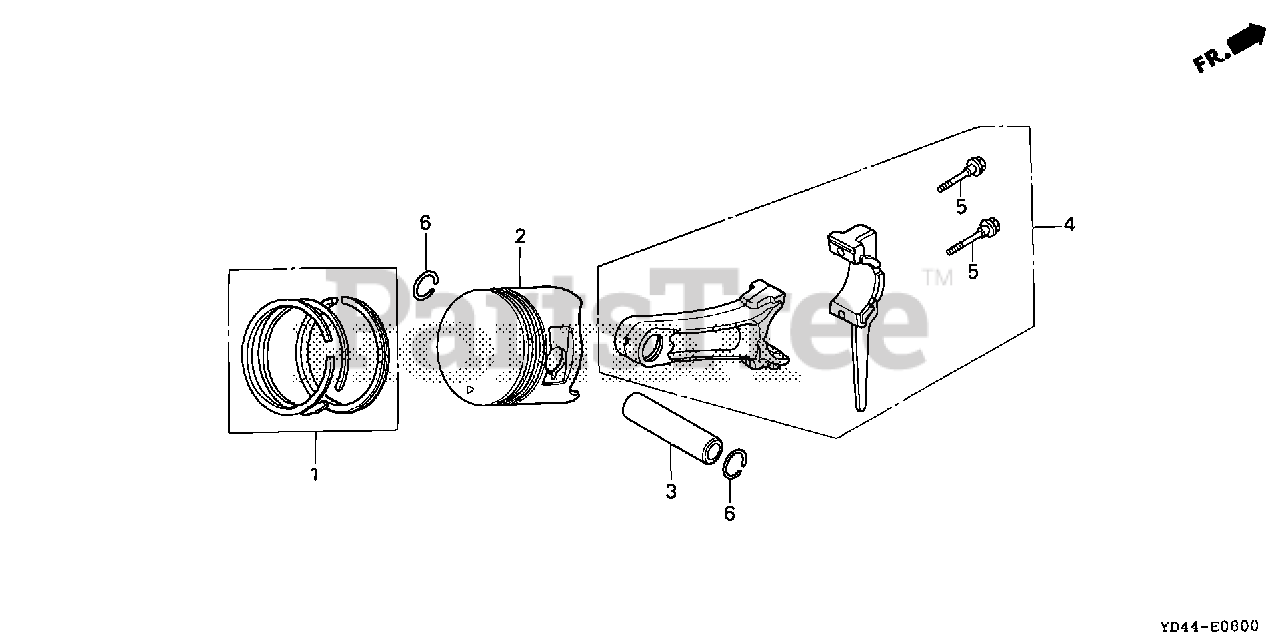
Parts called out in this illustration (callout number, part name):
1	RING SET, PISTON (STD) (TEIKOKU)
1	RING SET, PISTON (0.25) (TEIKOKU)
1	RING SET, PISTON (0.25) (RIKEN)
1	RING SET, PISTON (0.50) (TEIKOKU)
1	RING SET, PISTON (0.50) (RIKEN)
1	RING SET, PISTON (0.75) (TEIKOKU)
1	RING SET, PISTON (0.75) (RIKEN)
2	PISTON (STD)
2	PISTON (0.25)
2	PISTON (0.50)
2	PISTON (0.75)
3	PIN, PISTON
4	ROD ASSY., CONNECTING (STD)
4	ROD ASSY., CONNECTING (0.25 LOWER SIZE)
5	BOLT, CONNECTING ROD
6	CLIP, PISTON PIN (20MM)
